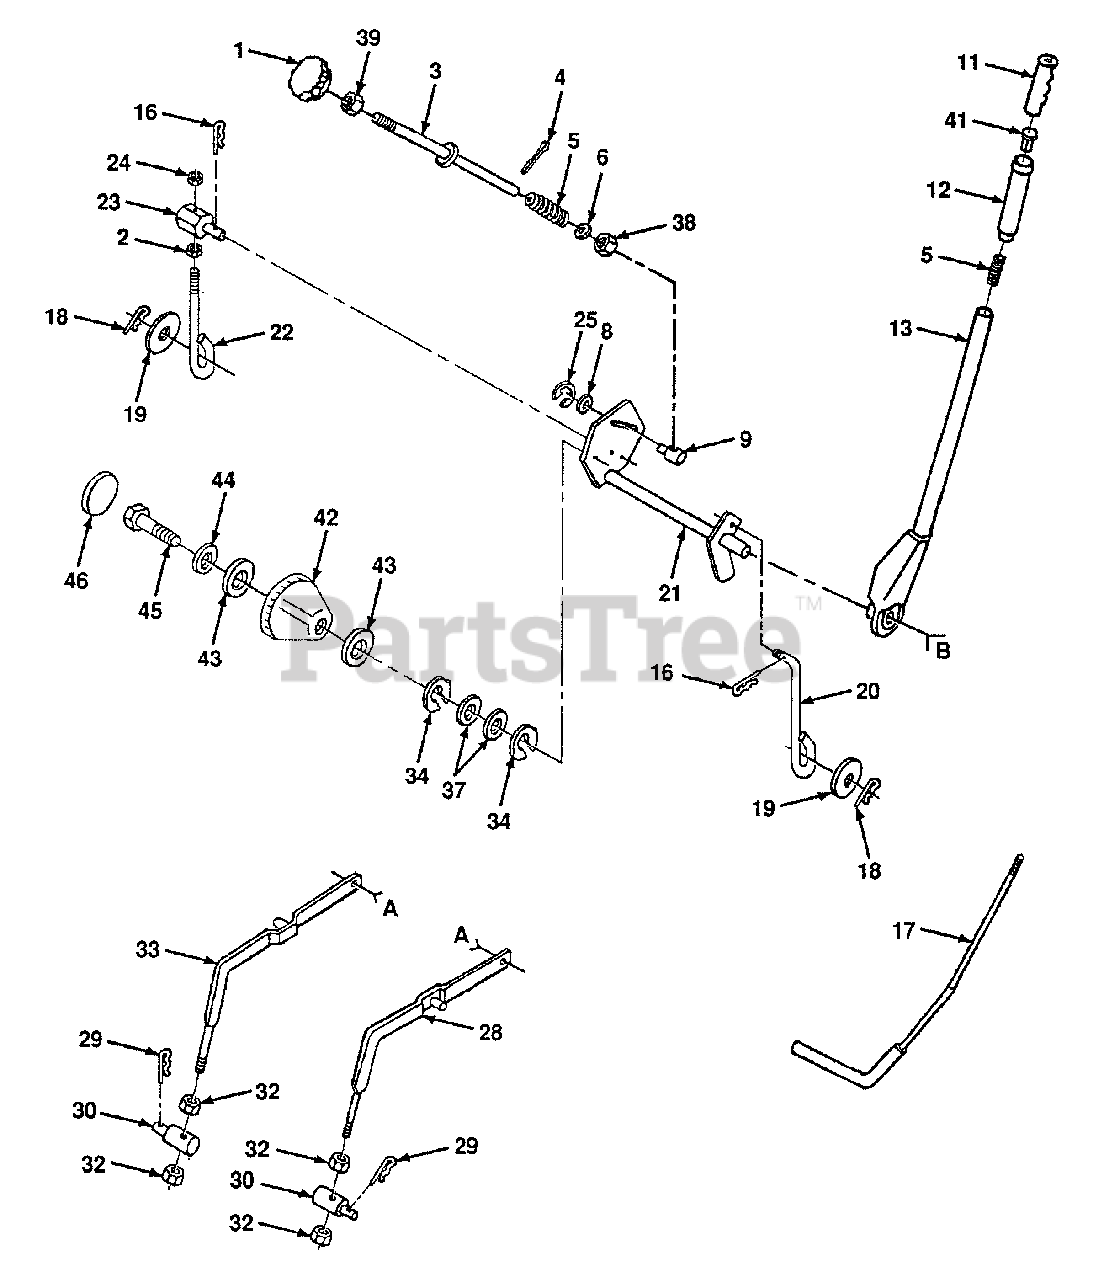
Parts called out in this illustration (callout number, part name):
1	Handle, Lift, Adjustment
2	Nut, Hex 3/8 - 16
3	Rod, Adjust, Lift
4	Pin, Cotter 3/32 x 1/2
5	Spring
6	Washer 13/32 x 5/8 x 16 Gauge
8	Washer 15/32 x 3/4 x 16 Gauge
9	Trunnion, Depth Stop
11	Grip, Handle
12	Plunger, Lever, Lift
13	Lever, Lift
16	Retainer, Spring
17	Rod, Lever
18	Retainer, Spring
19	Washer 17/32 x 15/16 x 16 Gauge
20	Link, Lift
21	Shaft, Lift, Assembly
22	Link, Lift, Adjust
23	Trunnion, Lift
24	Nut, Lock 7/16 -14
28	Arm, Suspension, R.H.
29	Retainer, Spring
30	Trunnion, Lift, Lower
32	Nut, Hex, Fin 1 /2 - 13
33	Arm, Suspension, L.H.
37	Washer 29/32 x 1-1/4 x 16 Gauge
38	Nut, Special
39	Nut, Hex, Jam 3/8 - 16 UNC
41	Button, Plunger
42	Scale, Height Indicator
43	Washer 11/32 x 1-1/2 x 10 Gauge
44	Washer, Lock, Hvy., Helical Spring
45	Bolt, Hex, Fin 5/16 -18 UNC x 1
46	Plug, Hole
